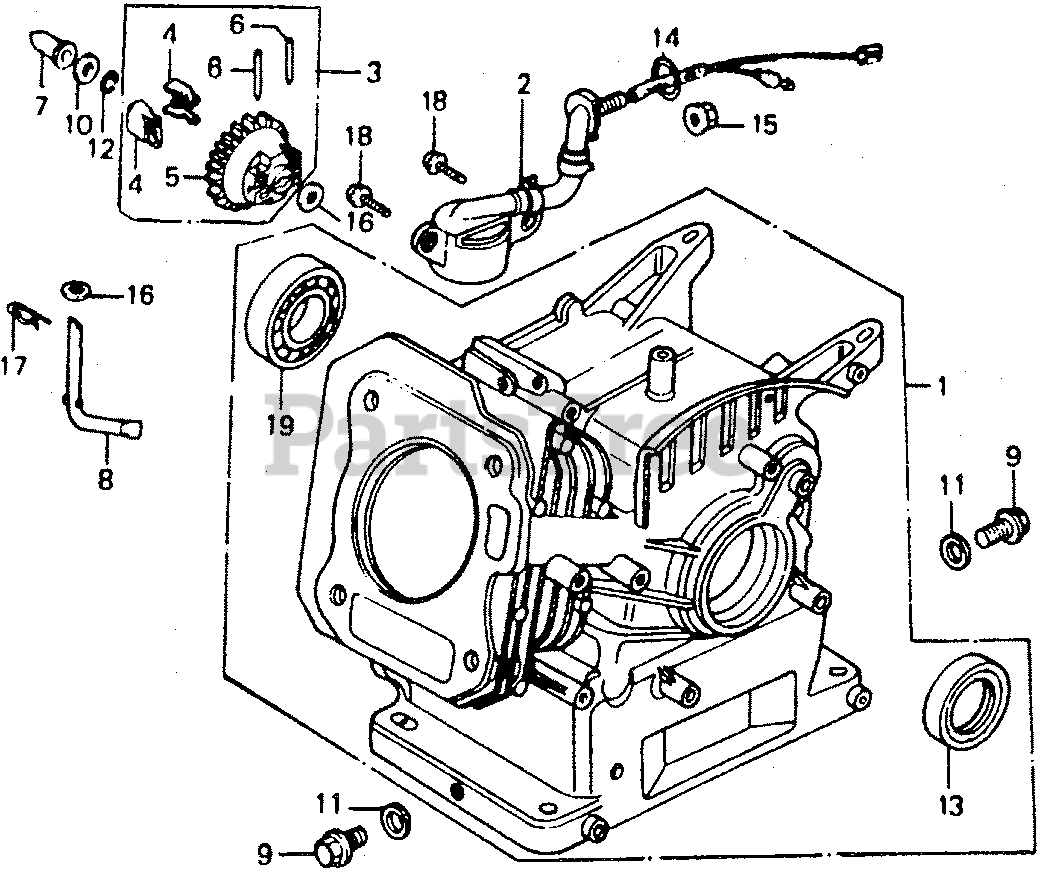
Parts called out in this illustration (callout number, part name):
1	CYLINDER ASSY. (OIL ALERT)
2	SWITCH ASSY., OIL LEVEL
3	GOVERNOR ASSY.
4	WEIGHT, GOVERNOR
5	HOLDER, GOVERNOR WEIGHT
6	PIN, GOVERNOR WEIGHT
7	SLIDER, GOVERNOR
8	SHAFT, GOVERNOR ARM
9	BOLT, DRAIN PLUG
10	WASHER, THRUST (6MM)
11	WASHER, DRAIN PLUG (10.2MM)
12	CLIP, GOVERNOR HOLDER
13	OIL SEAL (25X41X6)
14	O-RING (13.5X1.5) (ARAI)
15	NUT, FLANGE (10MM)
16	WASHER, PLAIN (6MM)
17	PIN, LOCK (8MM)
18	BOLT, FLANGE (6X12)
19	BEARING, RADIAL BALL (6205)
NI	GOVERNOR KIT
